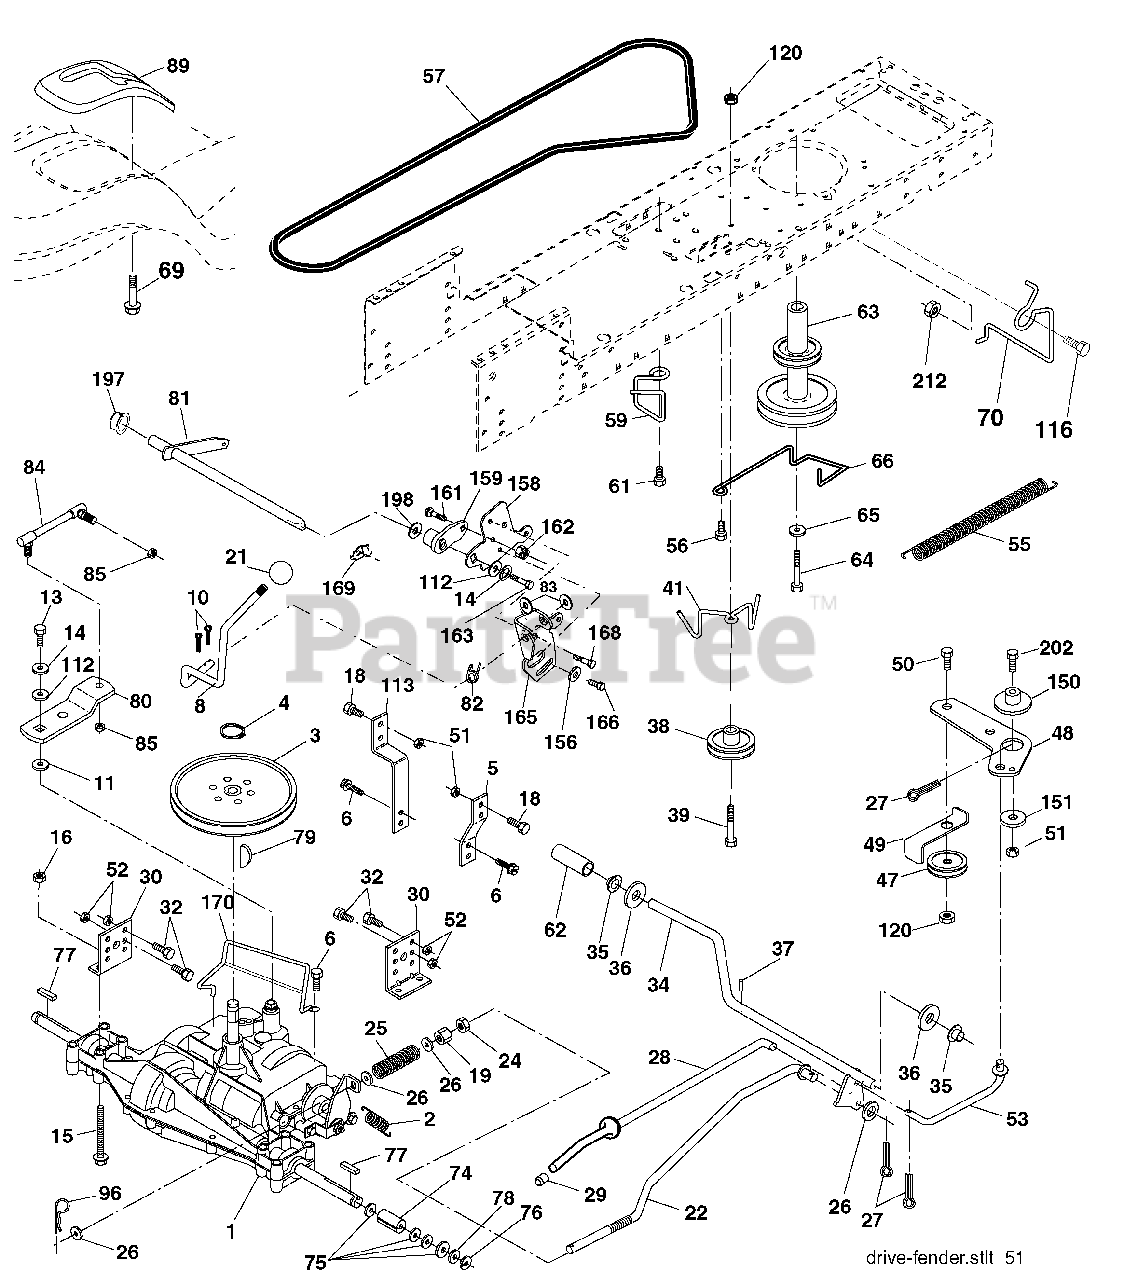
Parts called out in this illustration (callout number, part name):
2	Spring Return Brake
3	Pulley Transaxle 18"tires
4	Ring Retainer # 5100-62
5	Strap Torque 30 Degrees RH
6	Screw 5/16-18 x 3/4
8	Rod Shifter Blk
10	Pin Cotter 1/8 x 1 Cad
11	Washer Plate Shf 388 Sq Hole
13	Bolt 1/4-28 unf Gr. 8 w/Patch
14	Washer Lock Hvy Helical 1/4
15	Bolt Hex Flghd 5/16-18 Gr. 5
16	Nut 5/16-18
18	Bolt Fin Hex 3/8-16 unc x 1 Gr. 5
19	Nut lock Hex w/Ins 3/8-16 Unc
21	Knob
22	Rod Brake LT
24	Nut Hex Jam 3/8-16 unc
25	Spring Rod Brake 2 00 Zinc
26	Washer 13/32 x 13/16 x 16 Ga.
27	Pin Cotter 1/8 x 3/4 Cad
28	Rod Brake Parking LT/YT
29	Cap Brake Parking Black
30	Bracket Transmission
32	Bolt Fin Hex 5/16-18 x 3/4
34	Shaft Asm Pedal Foot Nibbed
35	Bearing Nylon Blk 629 Id
36	Washer 21/32 x 1 x 16 Ga.
37	Pin Roll 3/16 x 1"
38	Pulley Composite Flat
39	Bolt 3/8-16 x 2-3/4
41	Keeper Belt Idler
47	Pulley Idler V Groove Plastic
48	Bellcrank Clutch Grnd Drv STL
49	Retainer Belt Style Spring
50	Bolt Carr Sh 3/8-16 x 1-1/2 Gr. 5
51	Nut Crownlock 3/8-16 unc
52	Nut Crownlock 5/16-18 unc
53	Link Clutch
55	Spring Return Clutch 6 75
56	Screw 3/8-16 x 1-1/4
57	V-Belt Ground Drive 95
59	Keeper Belt Chassis Span Ctr
61	Screw 3/8-16 x .875
62	Cover Pedal Blk Round
63	Engine Pulley LT/YT
64	Bolt Hex 7/16-20 x 4 Gr. 5
65	Washer Lock Hvy Hlcl Spr 7/16
66	Keeper Belt Engine
69	Screw 1/4 x 1/2 unc
70	Guide Belt Mower Drive RH
74	Spacer Axle
75	Washer 25/32 x 1 1/4 x 16 Ga.
76	E-ring #5133-75
77	Key Square 2 0 x 1845/ 1865
78	Washer 25/32 x 1-5/8 x 16 Ga.
79	Key Woodruff
80	Arm Shift Transaxle
81	Shaft Asm Cross Taper
82	Spring Torsion Shift
83	Washer 17/32 x 3/4 x 16 Ga.
84	Link Transaxle
85	Nut Lock Center 1/4-28
89	Console Shift
96	Retainer Spring 1"
112	Washer 9/32 x 3/4 x 10 Ga.
113	Strap Torque 90 Degrees LH
116	Bolt Rdhd Sq Neck 3/8-16 x 1
120	Nut Lock Flg 3/8-16
150	Spacer Retainer Lt
151	Washer 13/32 x 2 x 10 Ga.
156	Washer Srrrtd 5/16 ID x 1.0 x .125
158	Bracket Shift Mount
159	Hub Shift
161	Bolt 1/4-20 x 3/4 Gr. 5
162	Nut Crownlock 1/4-20 unc
163	Bolt Hex Fin 1/4-20 unc x 1 Gr. 5
165	Bracket Pivot Lever
166	Screw 5/16-18 x 5/8
168	Bolt Shoulder 5/16-18 x .561
169	Plate Fastening
170	Keeper, Belt Transaxle
197	Nyliner Snap-In 5/8
198	Washer Nylon
202	Bolt Carr Sh 3/8-16 x 1-3/4 Gr. 5
212	Nut Hex Flg Lock
